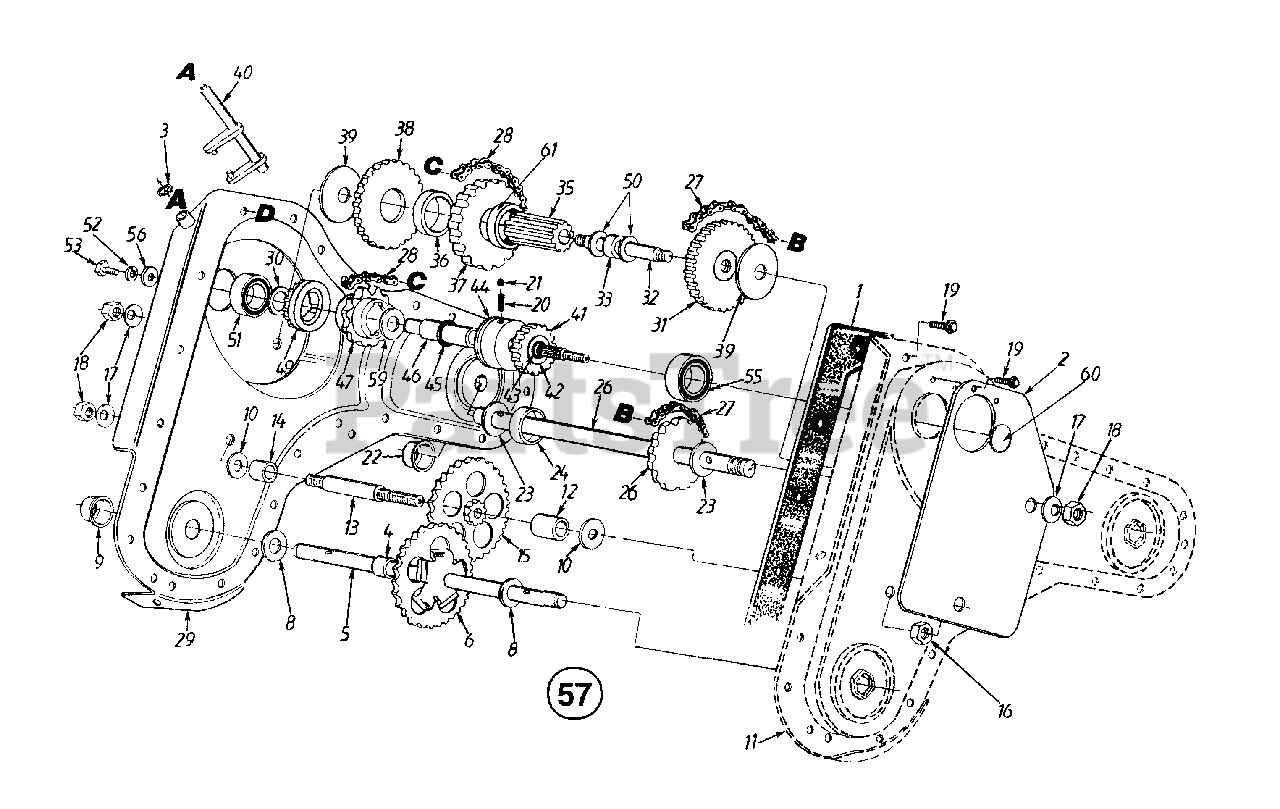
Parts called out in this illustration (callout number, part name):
1	Chain Case Gasket
3	Snap Ring
4	Spacer .735" I.D. x .886" O.D.
5	Wheel Shaft
6	Spur Gear 46T
8	Fl-Wash. .76" I.D. x 1.5" O.D.
9	Shaft Seal
10	Fl-Wash. 7/16" I.D. x 1-3/8" O.D.
13	Jack Shaft 2.06" Lg.
14	Spacer .635" I.D. x 1" O.D. x .37" Thk.
15	Gear Idler Ass'y.
16	Hex Patch L-Nut 7/16-20 Thd.
17	Bell-Wash. .45" I.D. x 1" O.D.
18	Hex Nut 7/16-20 Thd.
19	Hex Wash. Hd. TT-Tap Scr. 1/4-20 x .5" Lg.
20	Spring Detent
21	Ball Detent
22	Shaft Seal
23	Thrust Wash. 1.03" I.D. x 1.62"
24	Spacer 1" I.D. x 2" O.D. x .5" Thk.
26	Tine Shaft Ass'y.
27	Chain #50 5/8" Pitch x 52 Links-Endless
28	Chain-#41 1/2" Pitch x 30 Links-Endless
30	Fl-Wash. 7/16" I.D. x 1-3/8" O.D.
31	Gear and Sprocket Ass'y.
32	Jack Shaft 5" Lg.
33	Spacer .636" I.D. x .86" O.D.
35	Spur Gear 10T
36	Spacer 1.5" I.D. x 1.76" O.D.
37	Sprocket-#41 Chain
38	Reverse Gear 46T
39	Thrust Wash. .445" I.D. x 1.92"
40	Shifter Ass'y.
41	Spur Gear 17T
42	Fl-Wash. .69" I.D. x 1.06" O.D.
43	Wire Ring
44	Clutch Collar
45	Retaining Ring .875" Shaft
46	Drive Shaft
47	Sprocket 11T
49	Spur Gear 16T
50	Fl-Wash. 5/8" I.D. x 1" O.D.
51	Ball Bearing .669" I.D.
52	L-Wash. 1/4" I.D.
53	Hex Bolt 1/4-20 x .62" Lg.
55	Ball Bearing
56	Fl-Wash. .281" I.D. x .875" O.D.
57	Gear Case Ass'y. Comp.
59	Fl-Wash. .88" I.D. x 1.5" O.D.
60	Button Plug
61	Spacer 1.52" I.D.
